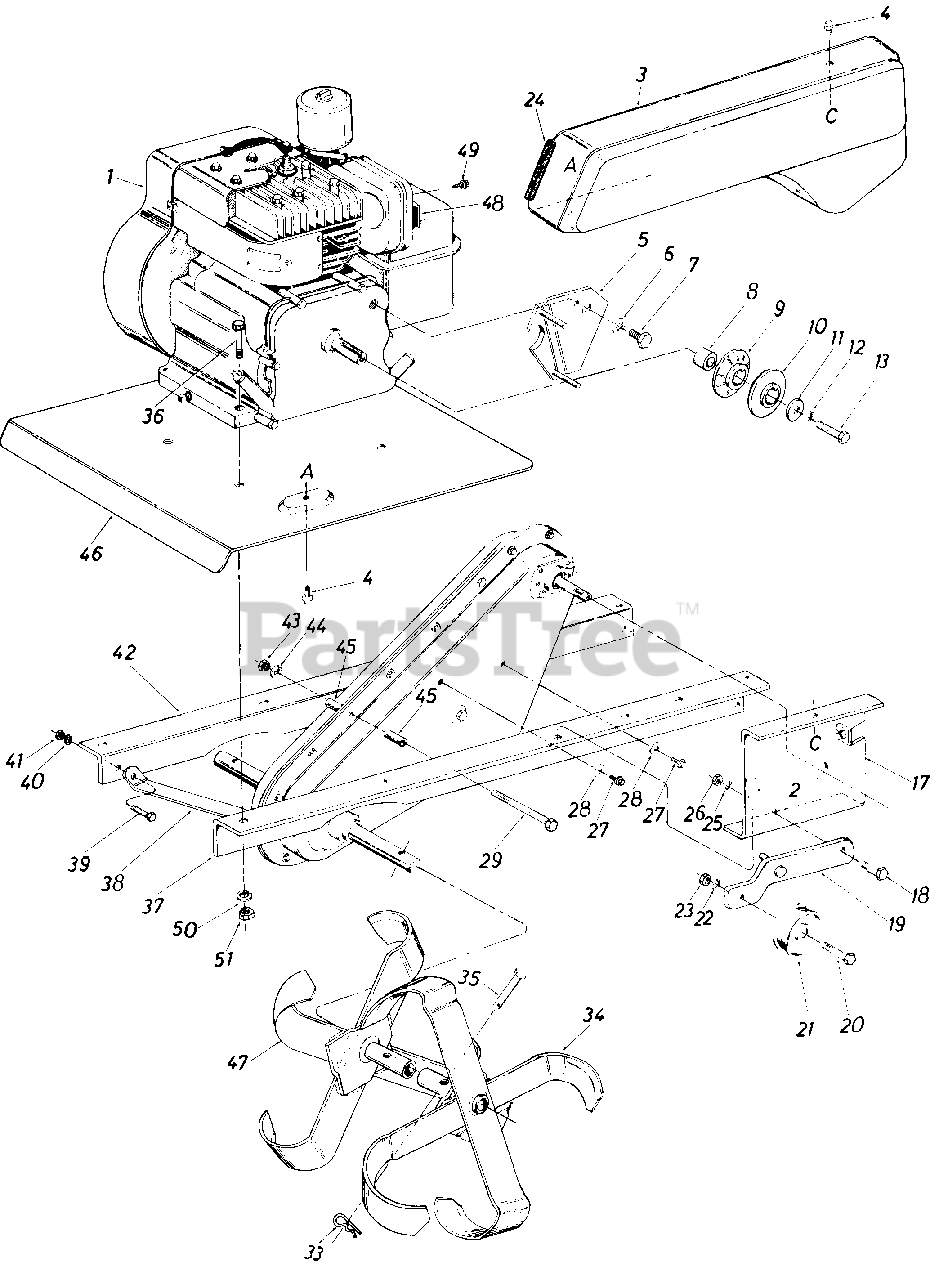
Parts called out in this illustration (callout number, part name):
1	Engine
2	Hex Wash. Hd. Self-Tap Scr. 5/16-24 x .50" Lg.
3	Belt Cover
4	Hex Wash. Hd. Self-Tap Scr. 1/4-20 x .50" Lg.
5	Belt Keeper Brkt. Ass'y.
6	Internal L-Wash. 1/2" I.D.
7	Hex Scr. 1/2-20 Thd.
8	Spacer
9	Pulley Half
10	Pulley Half
11	Fl-Wash 3/8 I.D. x 1.25" O D. x .100
12	L-Wash. 3/8" I.D.*
13	Hex Scr. 3/8-24 x 1.00" Lg.
17	Idler Mounting Brkt.
18	Shld. Bolt
19	Idler Bracket Ass'y.
20	Hex Scr. 3/8-16 x 1.50" Lg.
21	Idler Pulley
22	L-Wash. 3/8" I.D.*
23	Hex Jam Nut 3/8-16 Thd.
24	Trim Strip-3"
25	L-Wash. 3/8" I.D.*
26	Hex Jam Nut 3/8-16 Thd.
27	Hex Wash. Hd. Self-Tap Scr. 1/4-20 x .50" Lg.
28	Belleville Wash. .26 I.D. x .75 O.D. x .060
29	Hex Scr. 5/16-18 x 2.75" Lg.
33	Hairpin Cotter
36	Bolt 5/16-18 x 1.5" Lg.
37	Frame Rail-L.H.
38	Front Brace Brkt.
39	Hex Scr. 5/16-18 x .75" Lg.
40	L-Wash. 5/16" I.D.
41	Hex Cent. L-Nut 5/16-18 Thd.
42	Frame Rail-R.H.
43	Hex Cent. L-Nut 5/16-18 Thd.
44	L-Wash. 5/16" I.D.
45	Spacer
46	Tine Shield
47	See Tine Chart Below
49	Hex Self-Tap Scr. #8-32 x.38" Lg.
50	L-Wash. 5/16" I.D.
51	Hex Nut 5/16-18 Thd.
